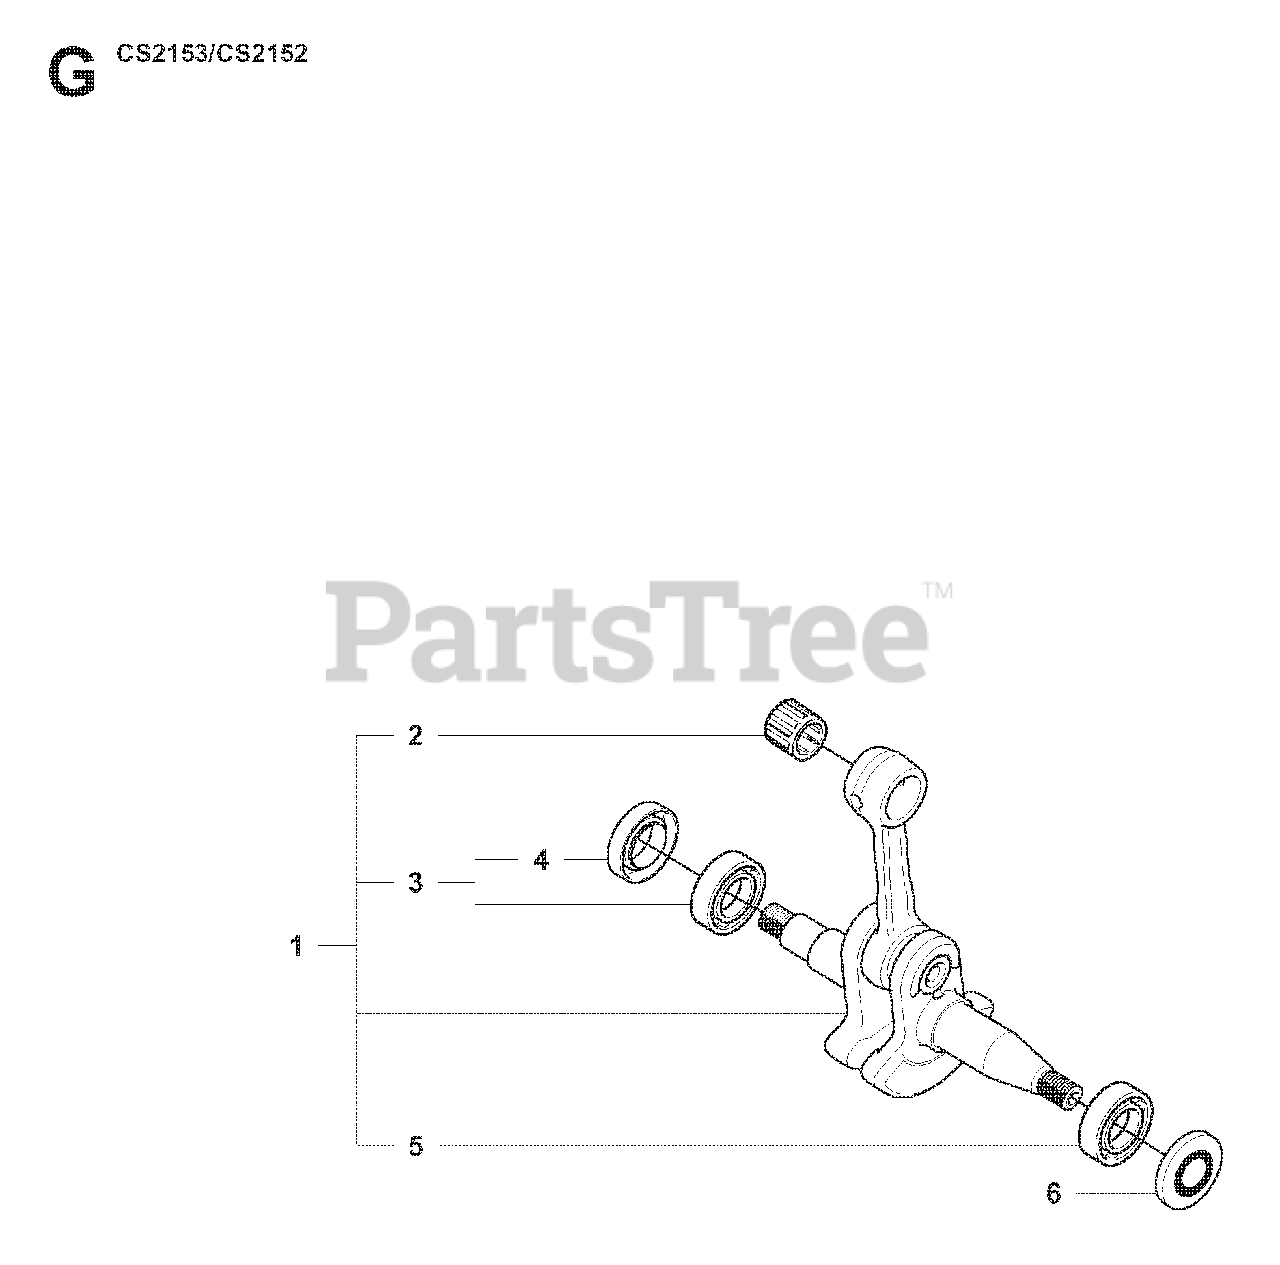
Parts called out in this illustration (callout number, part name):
1	CRANKSHAFT
2	RP SUPPORT BUSHING
3	%BEARING W/SEAL
4	SEALING
5	BALL BEARING-6202-C3 SKF
6	SEAL RING
